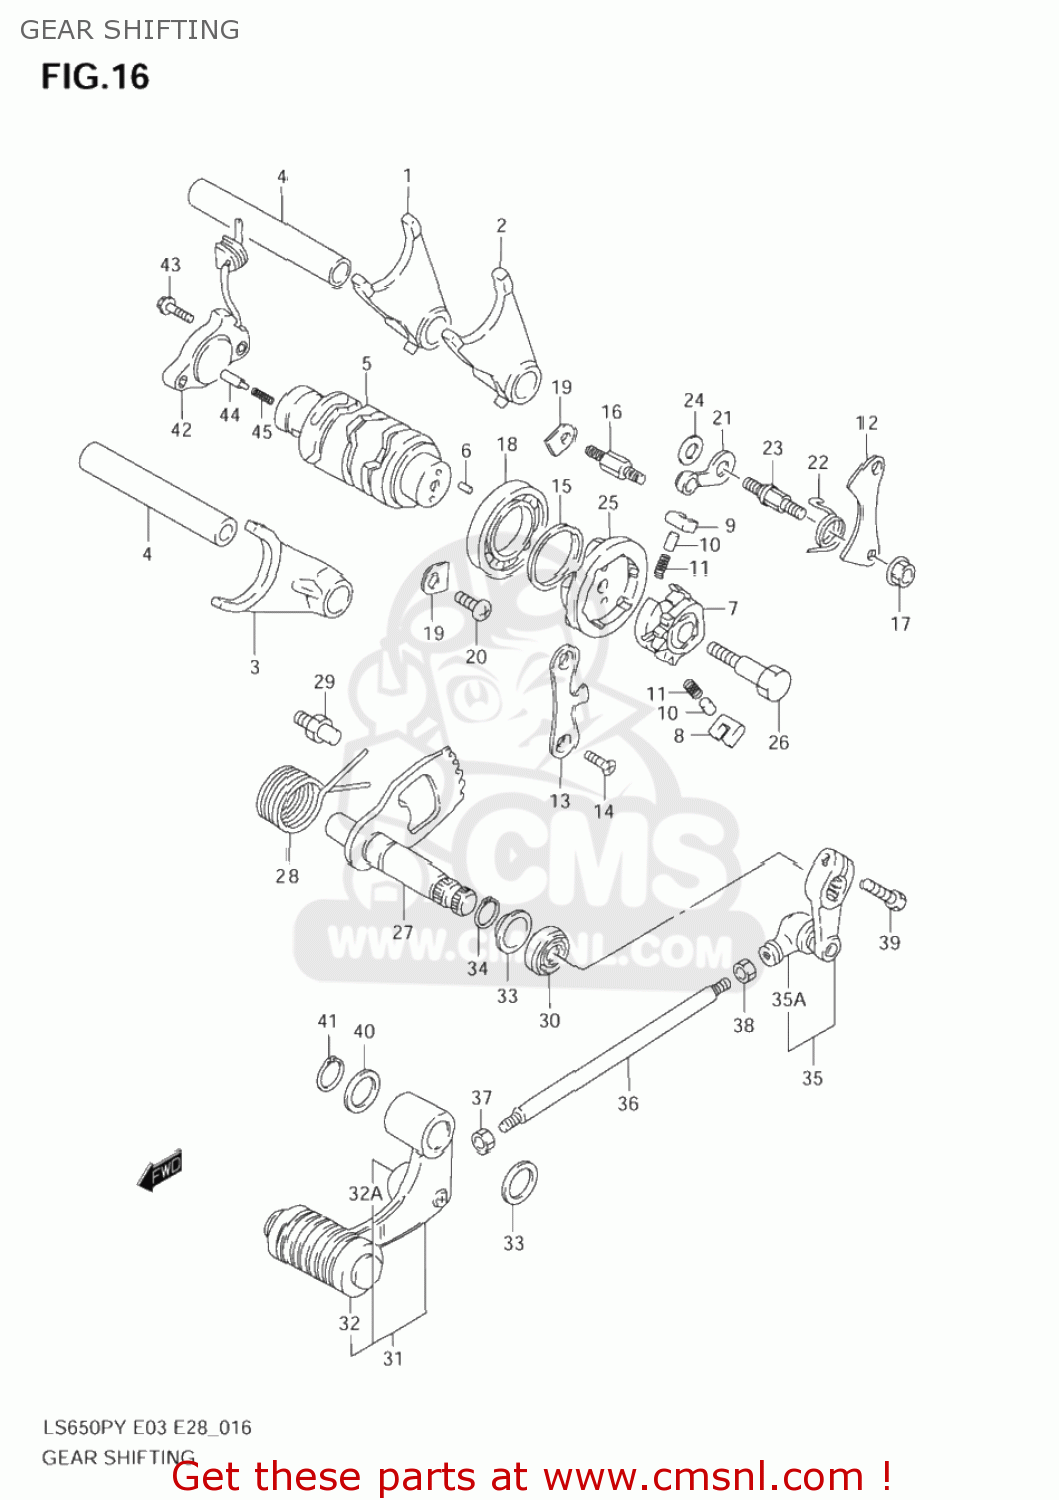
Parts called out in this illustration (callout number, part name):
1	FORK,GEAR SHIFT NO.1
2	FORK,GEAR SHIFT NO.2
3	FORK,GEAR SHIFT NO.3
4	SHAFT,GEAR SHIFT FORK
5	CAM,GEAR SHIFT
6	PIN
7	GEAR,GEARSHIFT CAM DRIVE
8	PAWL,GEAR SHIFT NO.1
9	PAWL,GEAR SHIFT NO.2
10	PIN(5X8)
11	SPRING
12	LIFTER,GEAR SHIFT POLE
13	GUIDE,GEAR SHIFT CAM
14	SCREW
15	WASHER(25X32X3)
16	BOSS,SHIFT PAWL LIFTER
17	NUT
18	BEARING(25X47X8)
19	RETAINER
20	SCREW
21	STOPPER,GEAR SHIFT CAM
22	SPRING
23	SUPPORT,CAM STOPPER ARM
24	WASHER
25	PLATE,GEAR SHIFT CAM
26	PIN,SHIFT CAM DRIVEN GEAR
27	SHAFT,GEAR SHIFT
28	SPRING
29	STOPPER,GEAR SHIFT ARM
30	OIL SEAL
31	LEVER ASSY,GEAR SHIFT
32	RUBBER,GEAR SHIFT PEDAL
32A	COVER,DUST
33	WASHER(12.5X20X1)
34	CIRCLIP,12 MM
35	ARM,GEAR SHIFT LINK
35A	COVER,DUST
36	ROD,GEAR SHIFT LINK
37	NUT
38	NUT 6MM
39	BOLT
40	WASHER
41	CIRCLIP,12 MM
42	BASE ASSY,NEUTRAL SW TERMINAL
43	SCREW
44	PIN(5X15.5)
45	SPRING
